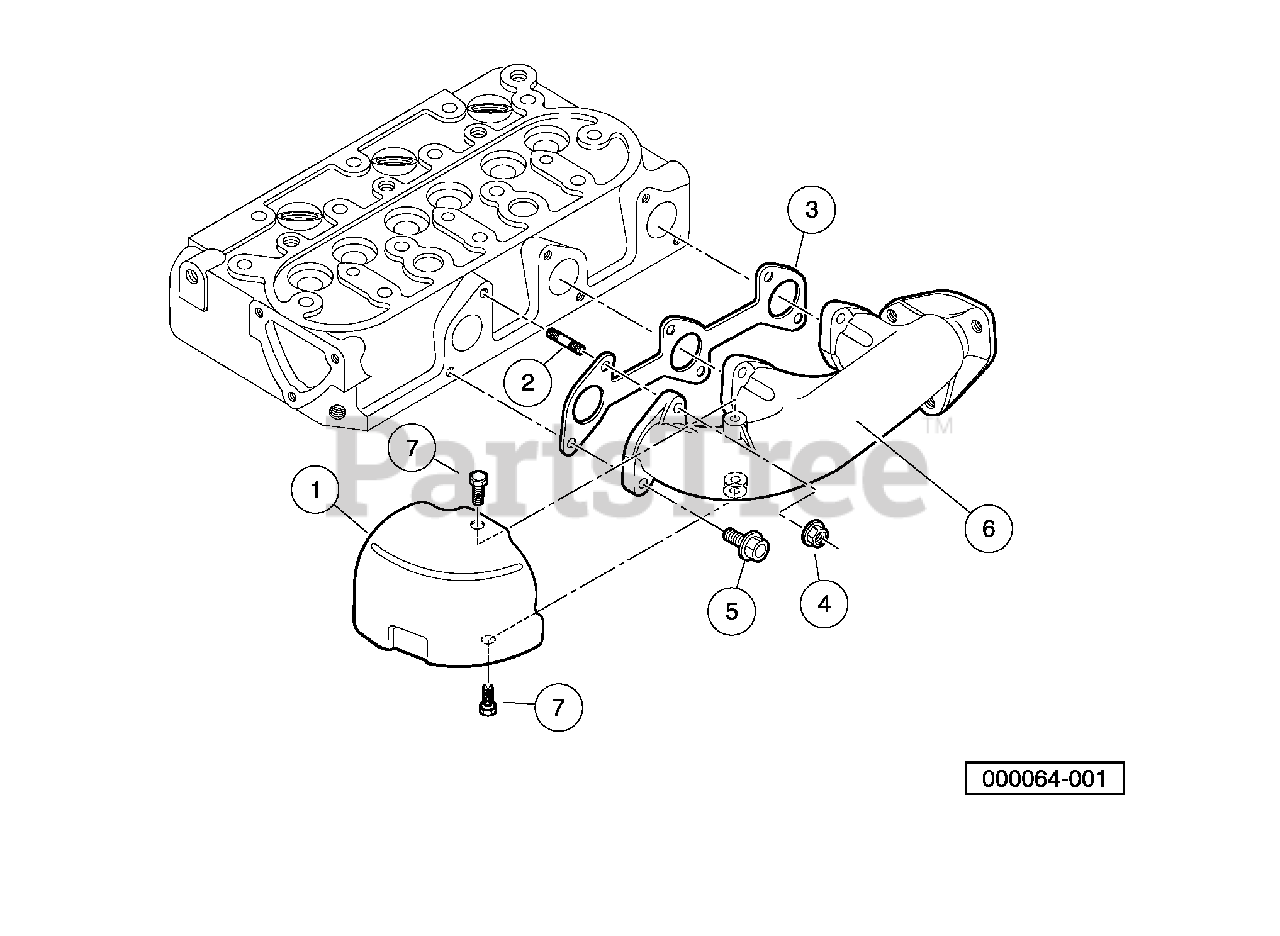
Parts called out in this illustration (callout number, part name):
1	Cover, Heat Proof
2	Stud, M6 X 26
3	Gasket, Ex-manifold
4	Nut, Flange, M6, Ubs
5	Bolt, Flange Head, M6 X 1 X 16
6	Manifold, Exhaust, D722
7	Bolt, D722, Exhst Manfld Cover
